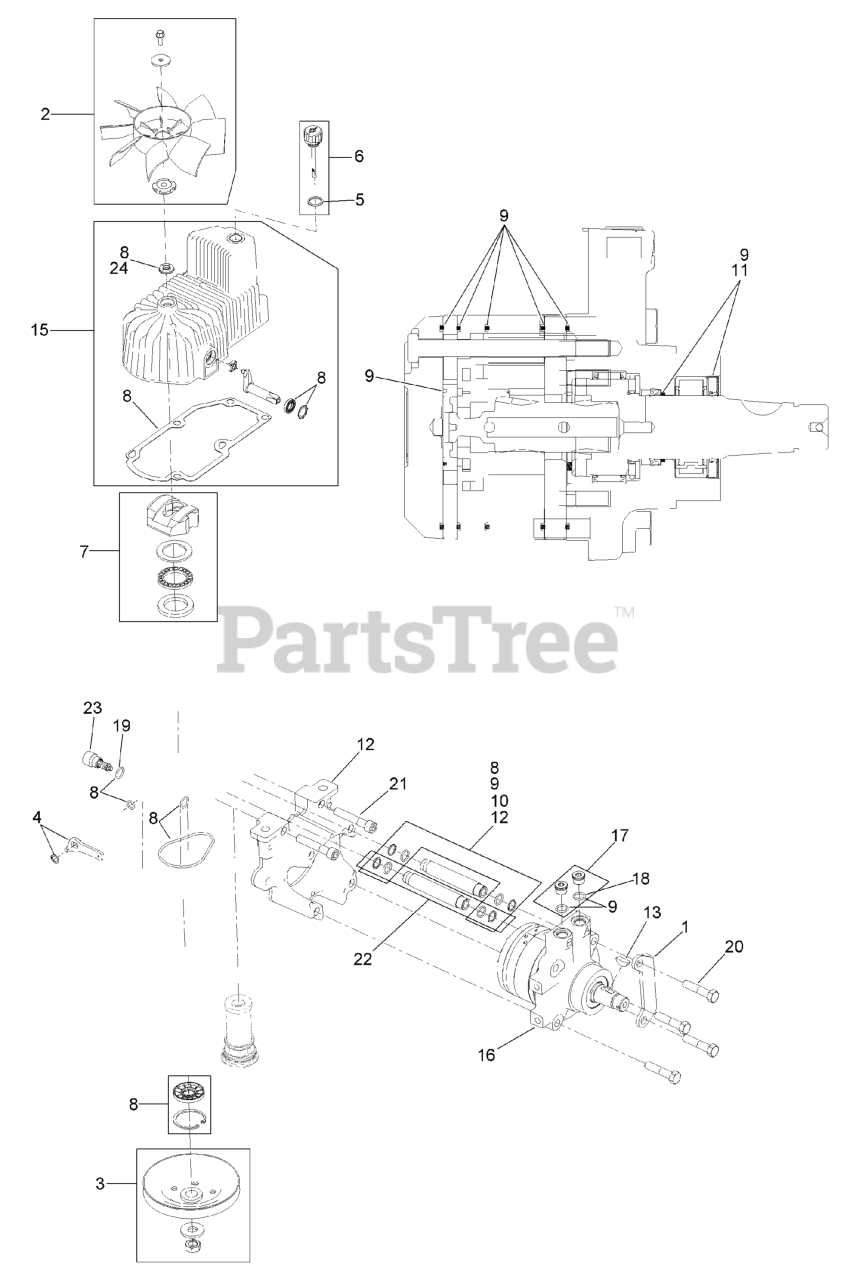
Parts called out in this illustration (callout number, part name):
1	MOUNT-SHOE, HORSE
2	FAN KIT
3	PULLEY KIT
4	HANDLE-BYPASS VALVE, HYDRO
5	GASKET-DIPSTICK, HYDRO
6	DIPSTICK-HYDRO W/GASKET
7	SWASH BLOCK KIT
8	PUMP SEAL KIT
9	MOTOR SEAL KIT
10	TUBE SEAL KIT
11	OUTPUT SHAFT SEAL KIT
12	NOSE CUP-UHT
13	KEY-WOODRUFF
15	HOUSING-HYDRO, RH
16	MOTOR-HYDRAULIC, RH 280CC
17	MAGNETIC PLUGS SERVICE KIT
19	O-RING-CHECK VALVE
20	SCREW HH
21	SCREW-HSH
22	HYDRAULIC TUBE KIT
23	SHOCK VALVE, 16CC HYDRO
24	SEAL-FAN DRIVE
25	Kit, Pump Section 16Cc RH
26	Kit, Rotating Grp 16Cc RH
99	PULLER-PULLEY
